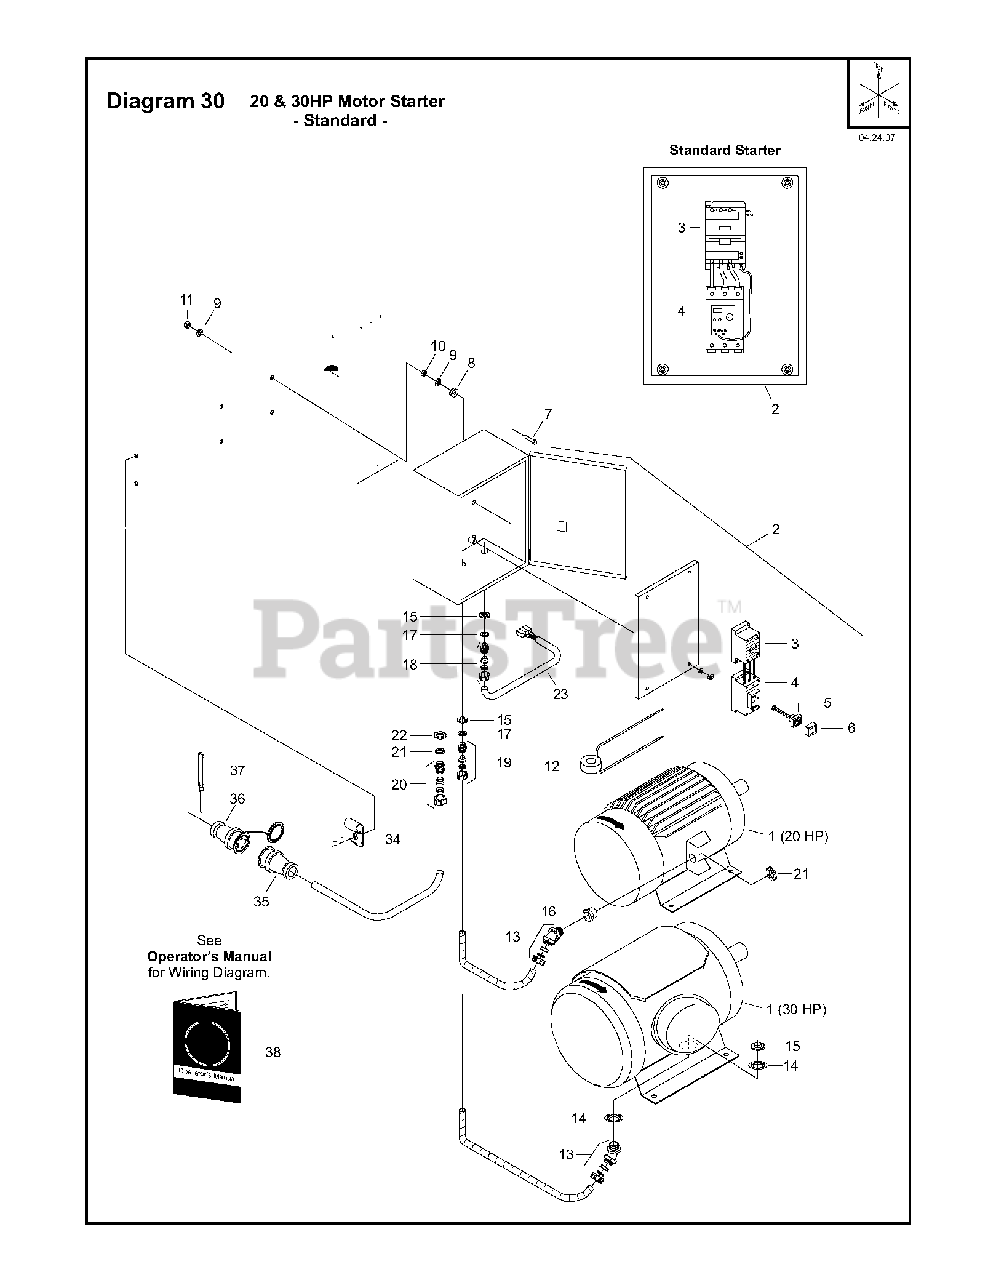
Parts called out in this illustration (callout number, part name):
5	RESET BUTTON THRU DOOR
6	RESET BUTTON COVER
7	HHCS. M8 X 1.25 X 40 DIN933 ZP
8	GROMMET
9	WASHER
10	NUT
11	LOCKNUT. FIBER M8 DIN 985 Z/P
12	TRNASFORMER: CURRENT
13	CONN: SEAL TIGHT 45 DEG 3/4"
14	REDUCING WASHER. CONDUIT
15	LOCK NUT. 3/4" CONDUIT
16	CONDUIT: FEMALE REDUCER
18	GRIP.STRT CORD WP .75IN SR-756
20	STRAIN RELIEF. WATER TIGHT 1/2
22	CONDUIT: LOCK NUT 1"
23	CONTROL CABLE: MTR PRO35III E
36	CONN: 230VAC ELEC WATER TIGHT
37	CABLE SUPPORT. BUS DROP
